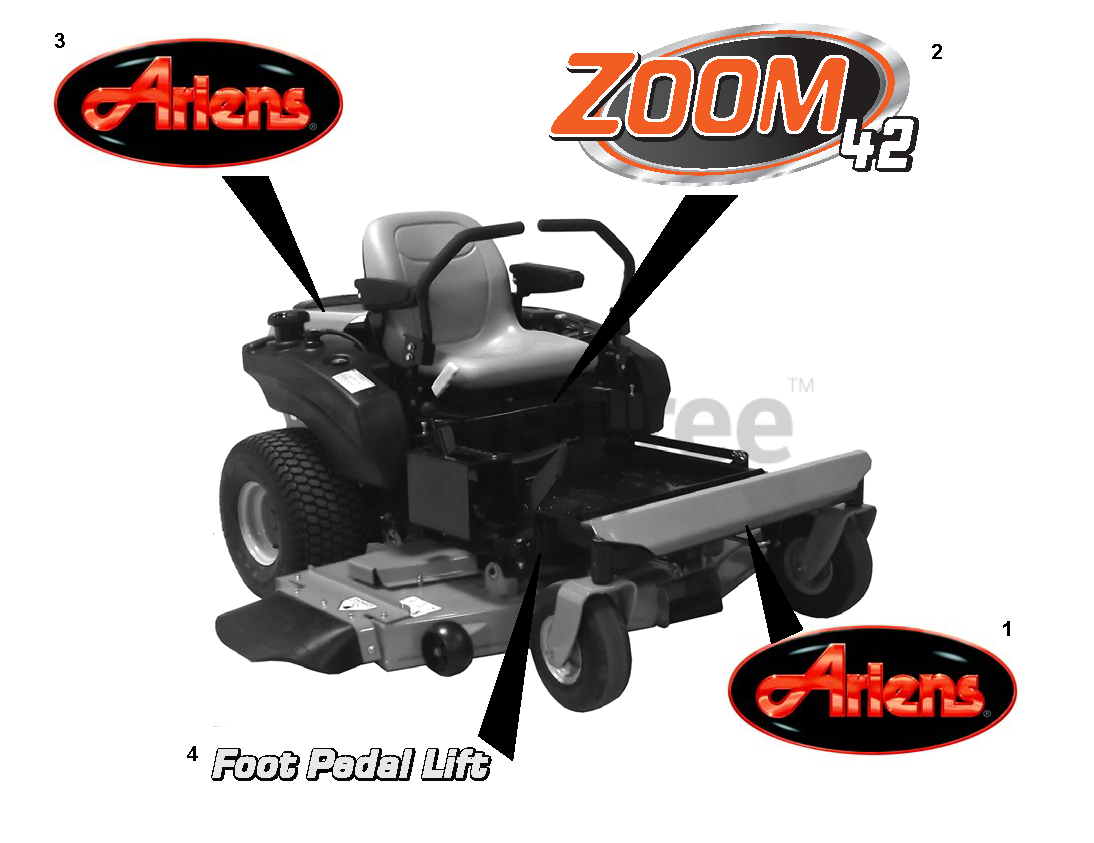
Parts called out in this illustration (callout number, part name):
1	DECAL, ARIENS JEWEL (LARGE)
2	DECAL, ZOOM42
3	DECAL, ARIENS JEWEL
4	DECAL, FOOT PEDAL LIFT
